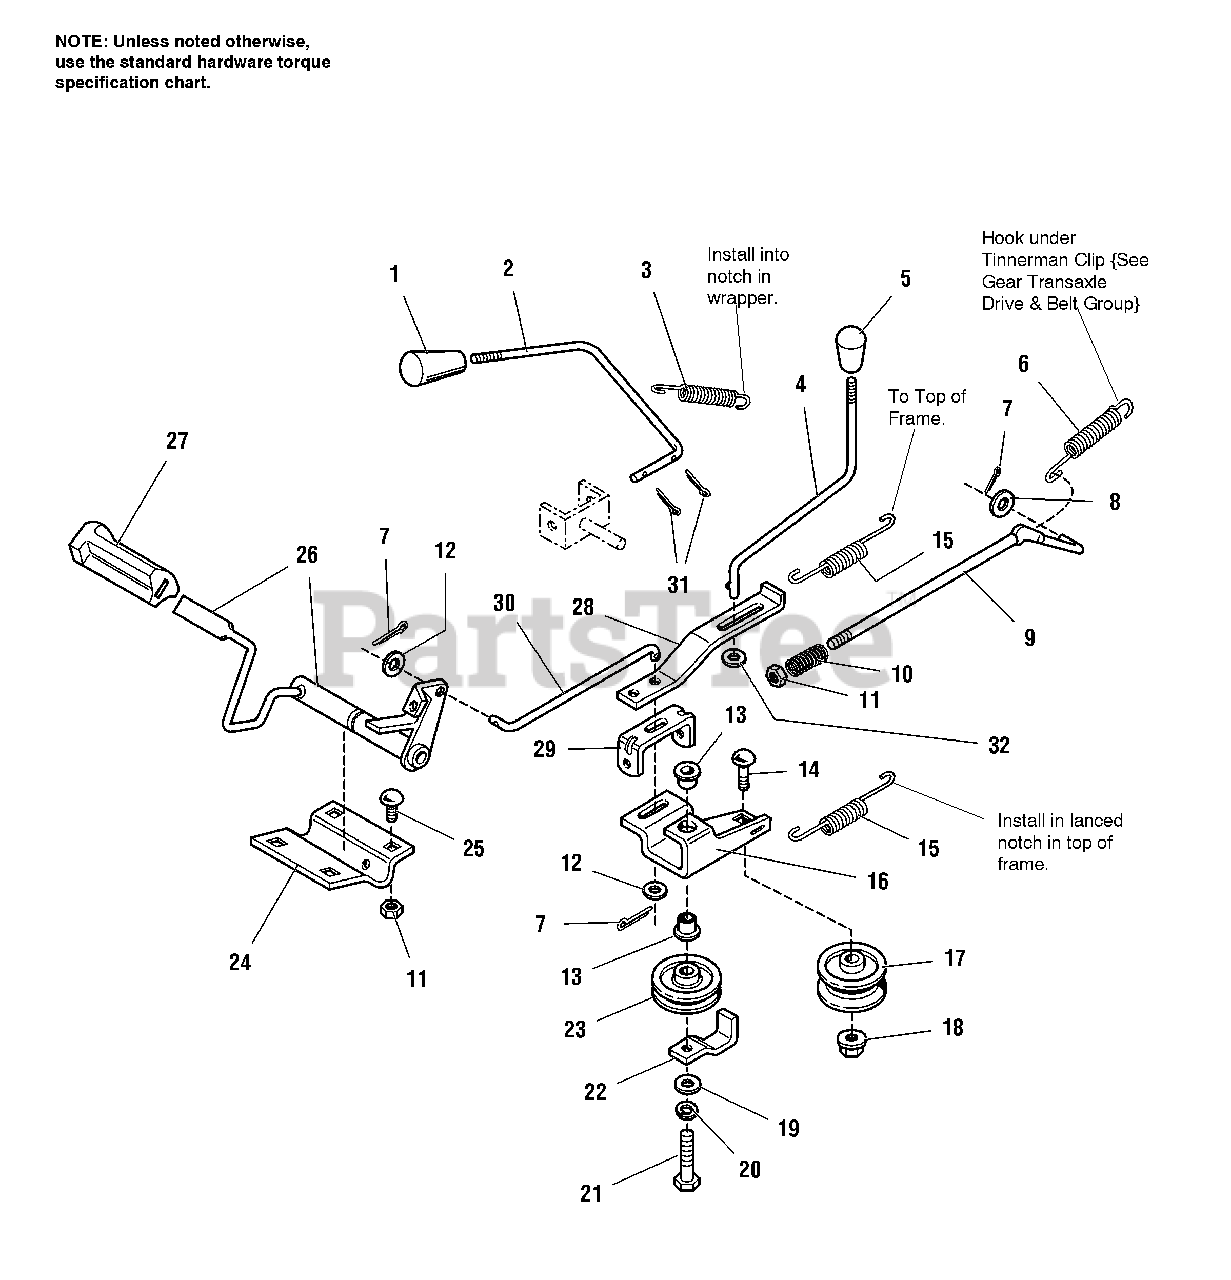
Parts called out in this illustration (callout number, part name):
1	KNOB, Plastic, Gear Shift
3	SPRING, Gear Shift
4	ROD, Parking Brake
5	KNOB, Plastic, Parking Brake
6	SPRING, Return
7	PIN, Cotter, 3/32 x 3/4
8	WASHER, Plain, 5/16
10	SPRING, Brake Rod
11	NUT, Hex Nylon Lock, 5/16-18
12	WASHER, Plain, 5/16
13	BUSHING, 5/8
14	CARRIAGE BOLT, 3/8-16 x 1-3/4
15	SPRING, Idler
16	BRACKET, Idler
17	PULLEY, Backside
18	NUT, Hex Flange Whiz Lock, 3/8-16
19	WASHER, Plain, 3/8
20	LOCKWASHER, 3/8
21	CAPSCREW, Hex Hd, 3/8-16 x 1-3/4
23	PULLEY, Idler, V
24	CLAMP, Tube
25	CARRIAGE BOLT, 5/16-18 x 3/4
26	FOOT PEDAL ASSEMBLY
27	PAD, Brake Pedal
28	LEVER, Parking Brake
29	GUIDE, Brake Rod
30	ROD, Clutch
31	PIN, Cotter, 3/32 x 1
32	WASHER, Plain, 1/4
